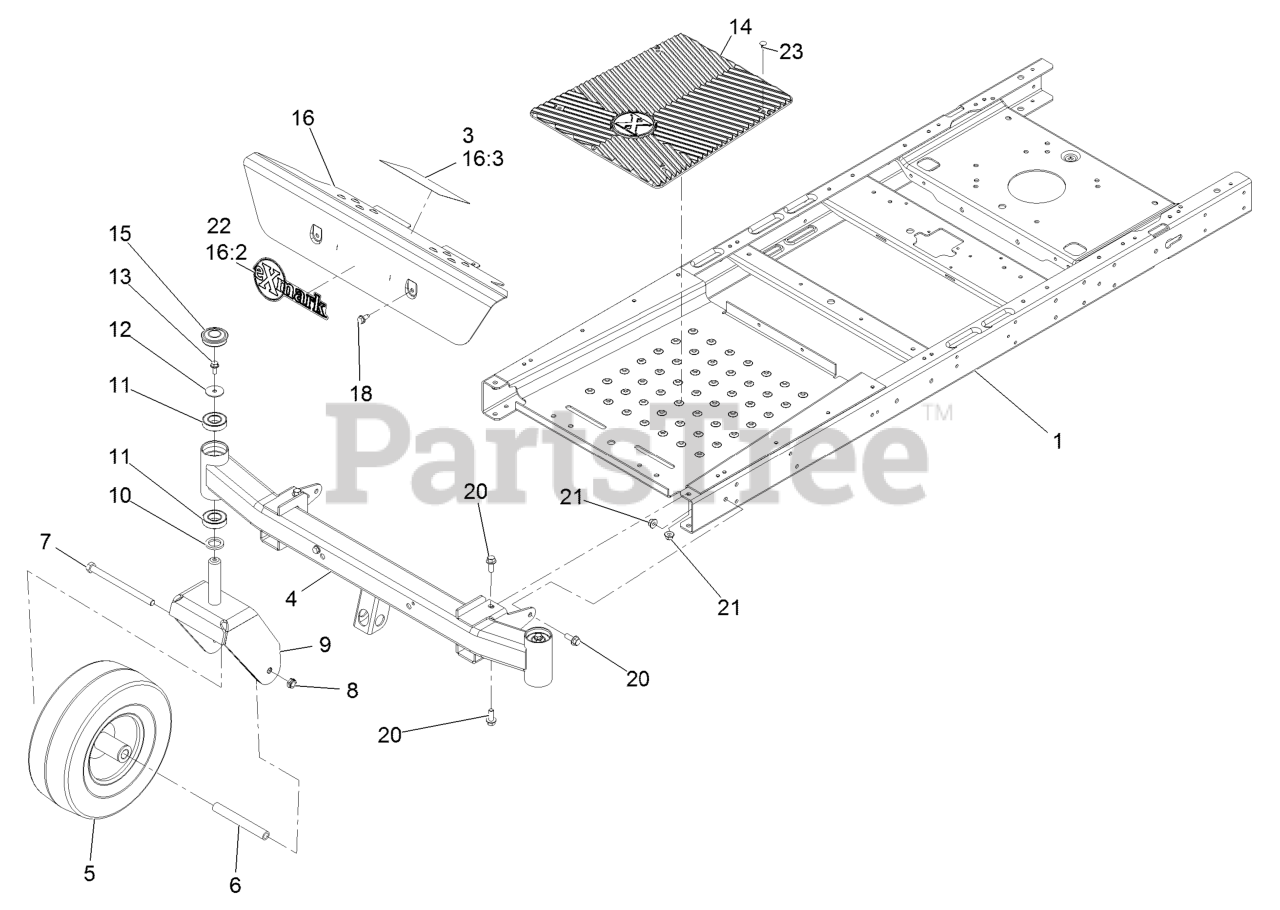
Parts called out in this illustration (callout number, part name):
1	FRAME ASM
3	DECAL-DANGER
5	13 INCH WHEEL AND TIRE AS
6	SPANNER
7	WASHER-LOCK
8	NUT-HEX
9	FORK-CASTER
10	WASHER-THRUST
11	BEARING-BALL
12	WASHER-FLAT
13	SCREW-HHF
14	FLOOR MAT- EXMARK
15	CAP-GREASE
16	FOOTREST ASM
16:2	DECAL-EXMARK LOGO
16:3	DECAL-DANGER
18	Screw-HWH 5/16-18 X 3/4 Tf
20	SCREW-HHF 3/8-16 X 1
21	NUT-HF, NI
22	DECAL-EXMARK LOGO
23	PLUG-PLASTIC
